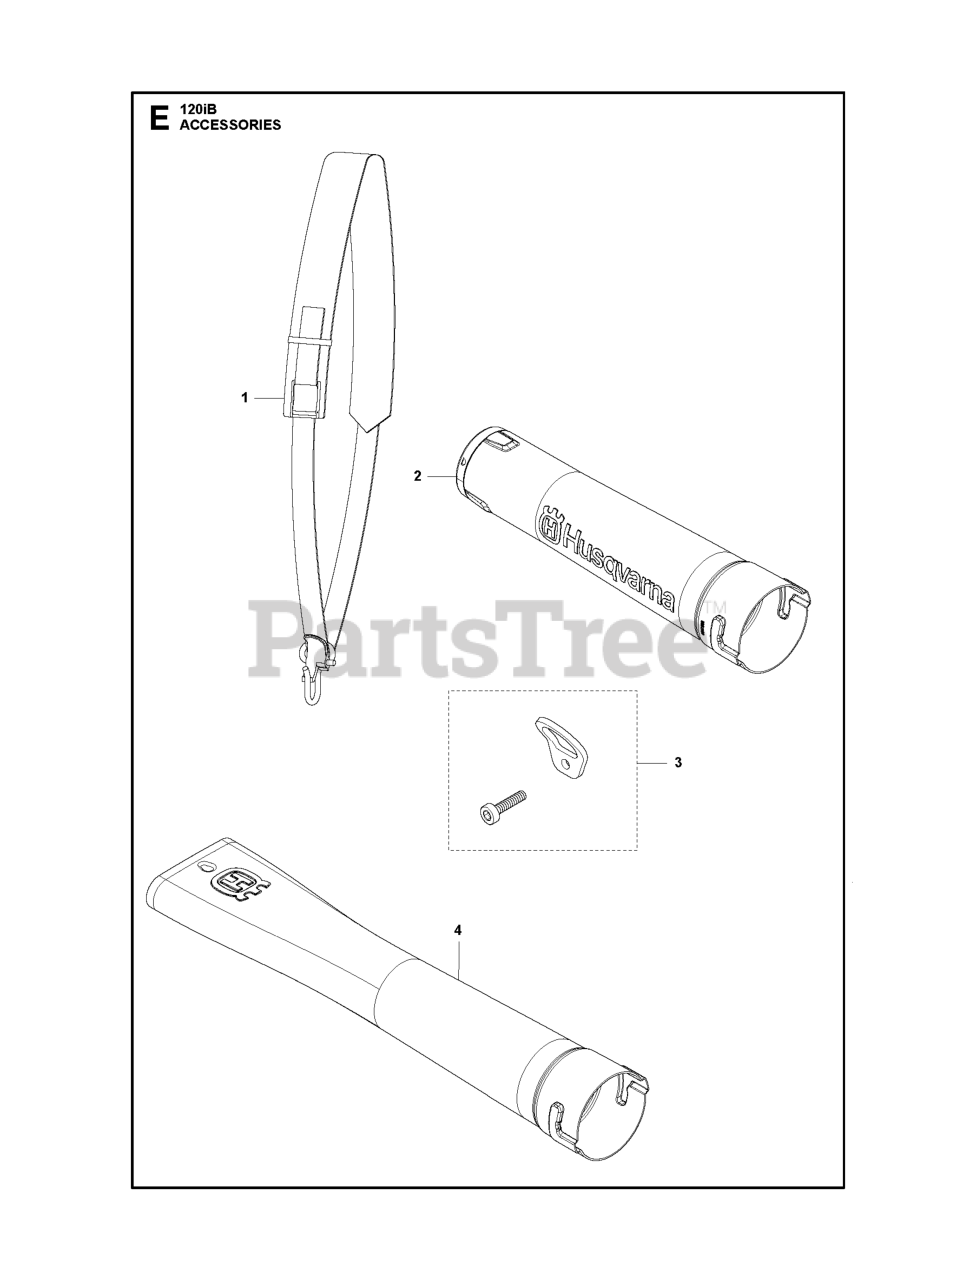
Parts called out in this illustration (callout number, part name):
1	Harness-w/o warning
2	TUBE ASSY NOZZLE 536LIBX
3	KIT EYELET
4	BLOWER NOZZLE FOR 320IB
